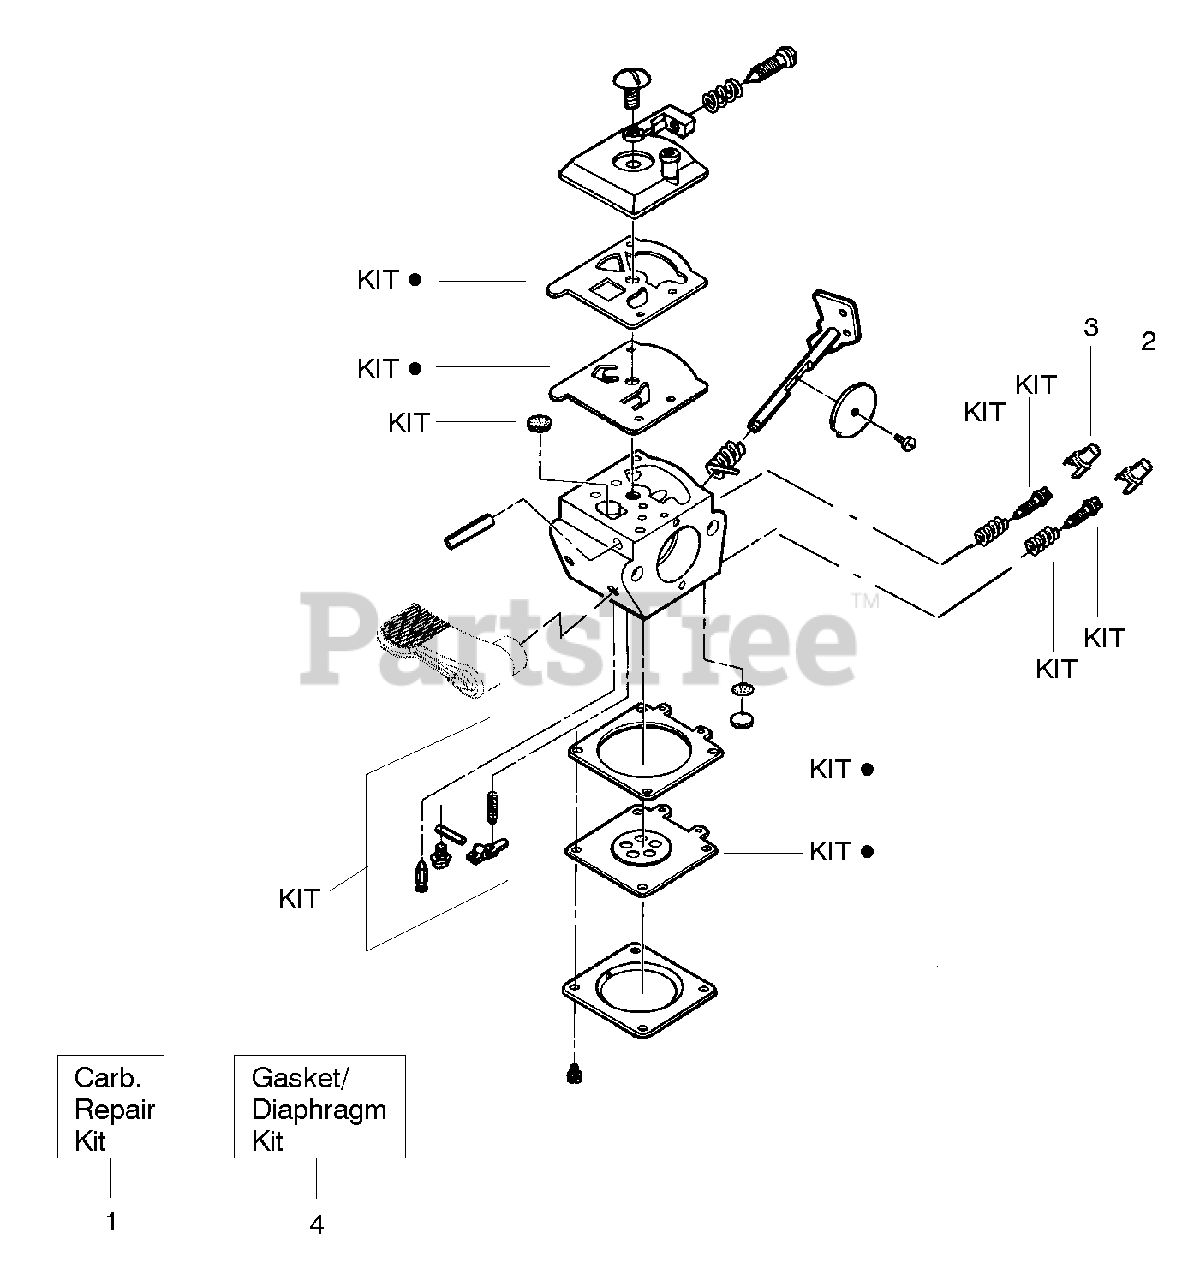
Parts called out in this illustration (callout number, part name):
1	Carburetor Repair Kit (KIT= Indicates Contents)
2	Limiter Cap-Low (tan)
3	Limiter Cap-High (brown)
4	Gasket/Diaphragm Kit (Indicates Contents)
